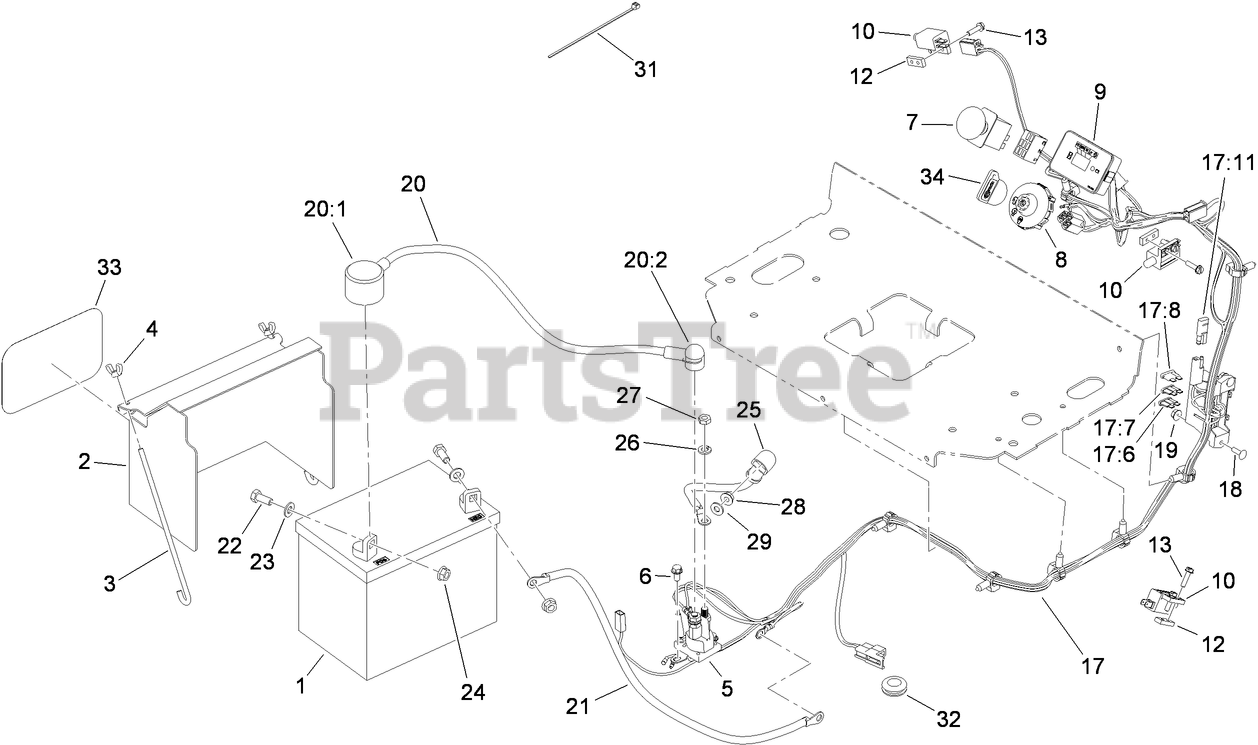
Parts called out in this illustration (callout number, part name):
1	BATTERY
2	COVER-BATTERY
3	BOLT-HOLDDOWN
4	WINGNUT
5	SOLENOID
6	SCREW-HWH
7	SWITCH-PTO, ON-ON-(ON)
8	SWITCH-IGNITION
9	MODULE-METER, HOUR
10	SWITCH-CLOSED, NORMALLY
12	PLATE-TAPPED
13	SCREW-HWH
17	HARNESS-WIRING
17:6	FUSE-BLADE, 30 AMP
17:7	FUSE-BLADE, 25 AMP
17:8	FUSE-BLADE, 10 AMP
17:11	CAP-PLUG
18	BOLT-CARR
19	NUT-HF
20	POSITIVE BATTERY CABLE ASM
20:1	INSULATOR-BATTERY
20:2	INSULATOR-SOLENOID
21	CABLE-BATTERY, BLACK
22	SCREW-HH
23	WASHER-PLAIN
24	NUT-HHF, SMOOTH
25	CABLE-BATTERY, RED
26	WASHER-LOCK
27	NUT-JAM
28	NUT-HF
29	WASHER-FLAT
31	TIE-CABLE
32	GROMMET
33	DECAL
34	KEY-IGNITION
